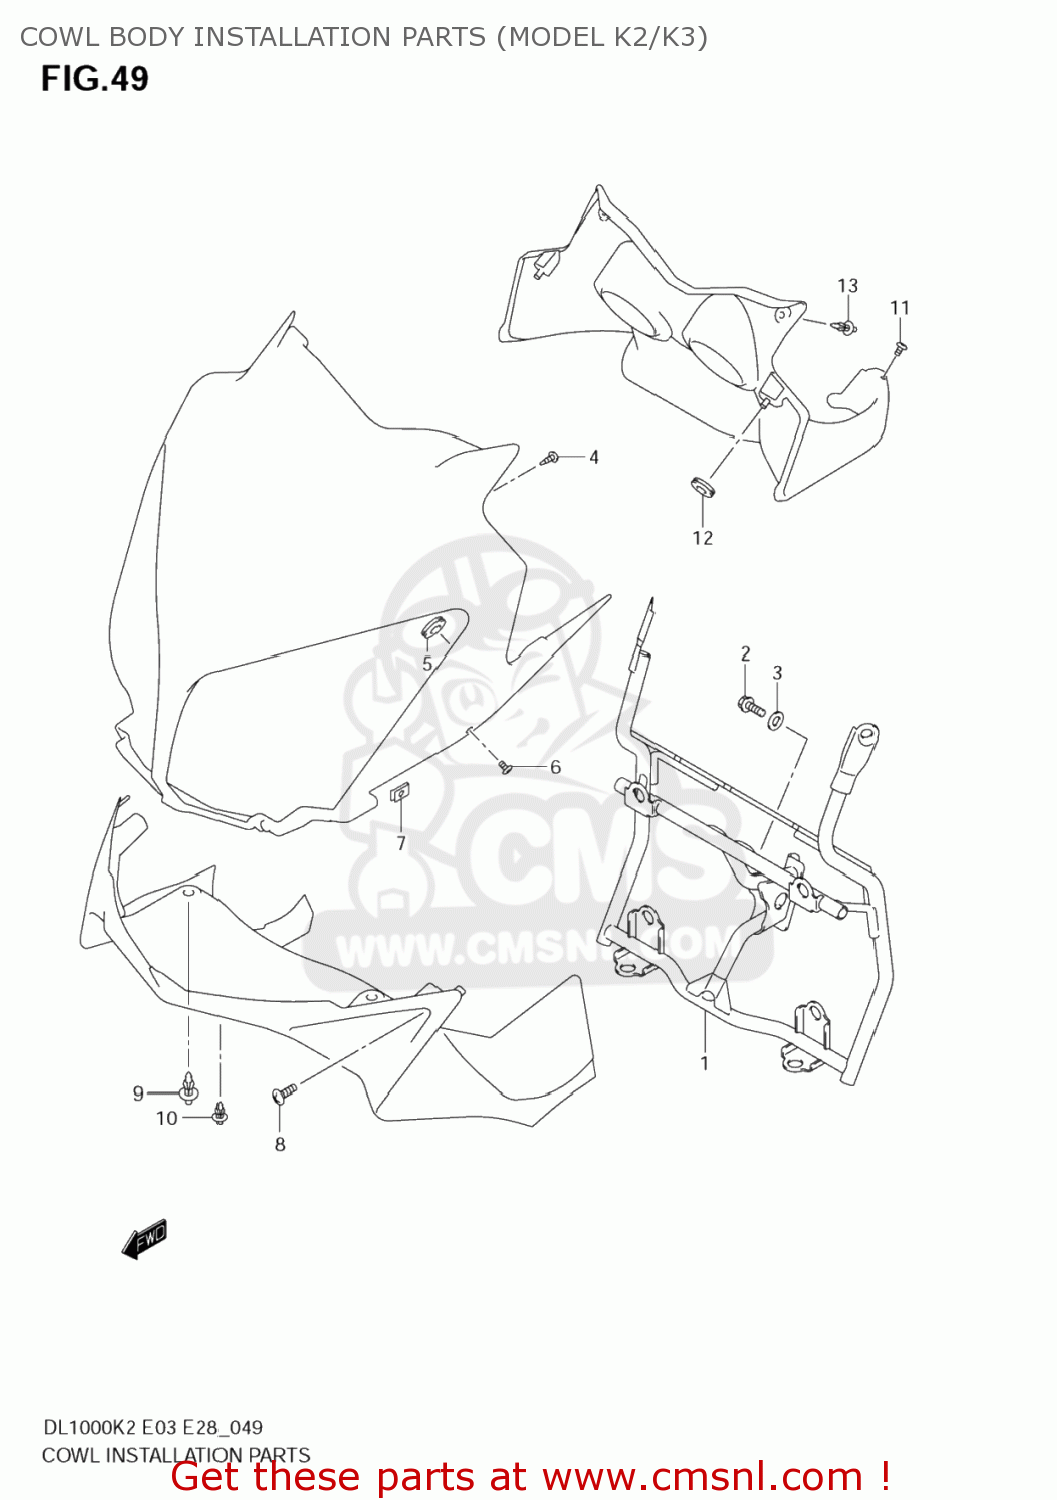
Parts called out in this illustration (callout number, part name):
1	BRACE COMP,COW
2	BOLT(8X20)
3	WASHER
4	SCREW(5X16)
5	CUSHION
6	SCREW(5X13)
7	NUT
8	SCREW
9	CLIP
10	CLIP(BLACK)
11	SCREW(6X10)
12	CUSHION
13	CLIP(BLACK)
